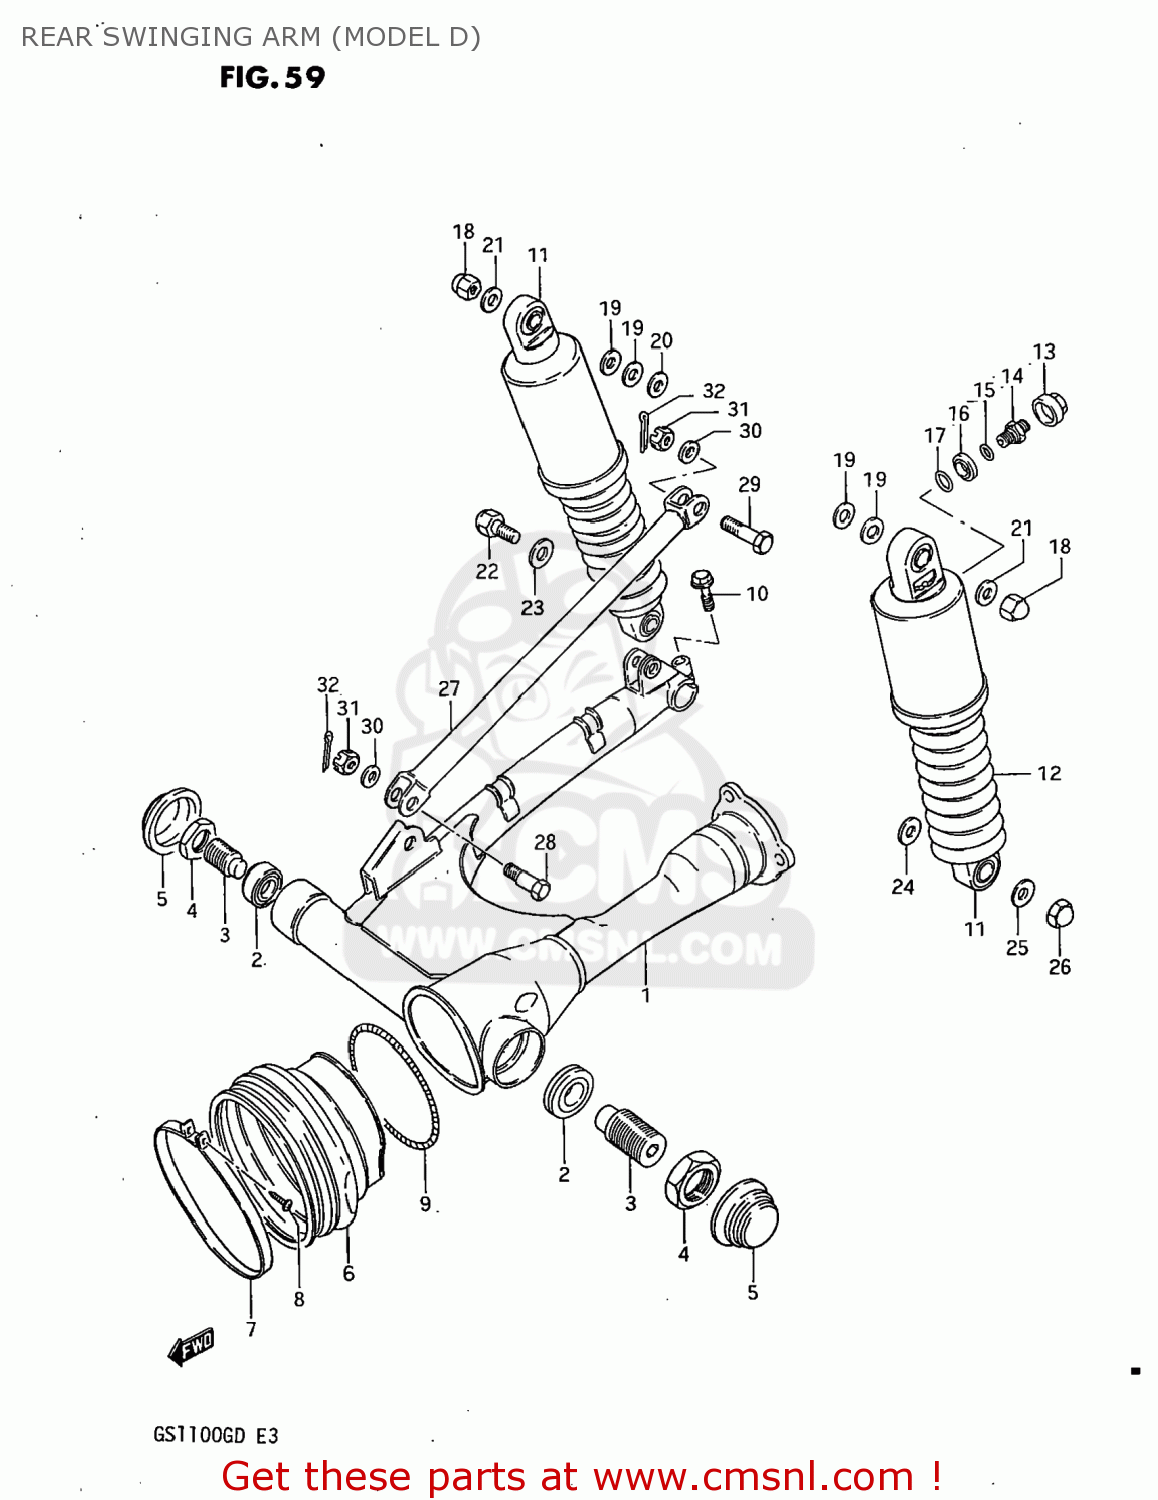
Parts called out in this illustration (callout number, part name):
1	SWING ARM SET,REAR (B
2	BEARING(17X40X13.25)
3	BOLT,REAR SWING ARM PIVOT
4	NUT
5	CAP,REAR SWING ARM PIVOT
6	BOOT,PROPELLER SHAFT
7	CLAMP
8	SCREW 4X25
9	SPRING,PROPELLER SHAFT
10	BOLT
11	ABSORBER ASSEMBLY,REAR SHOCK
12	BOOT,RR SHOCK
13	CAP,VALVE
14	VALVE,FRONT FORK AIR
15	O-RING
16	SPACER,REAR SHOCK ABSORBER
17	O RING,RR SHOCK
18	NUT
19	WASHER
20	WASHER (12.5X24X3.2)
21	WASHER
22	BOLT 12X33
23	WASHER (12.5X24X1.6)
24	WASHER
25	WASHER
26	NUT, LOWER LH
27	TORQUE LINK,REAR
28	BOLT
29	BOLT(10X39)
30	WASHER
31	NUT
32	PIN 20X20
